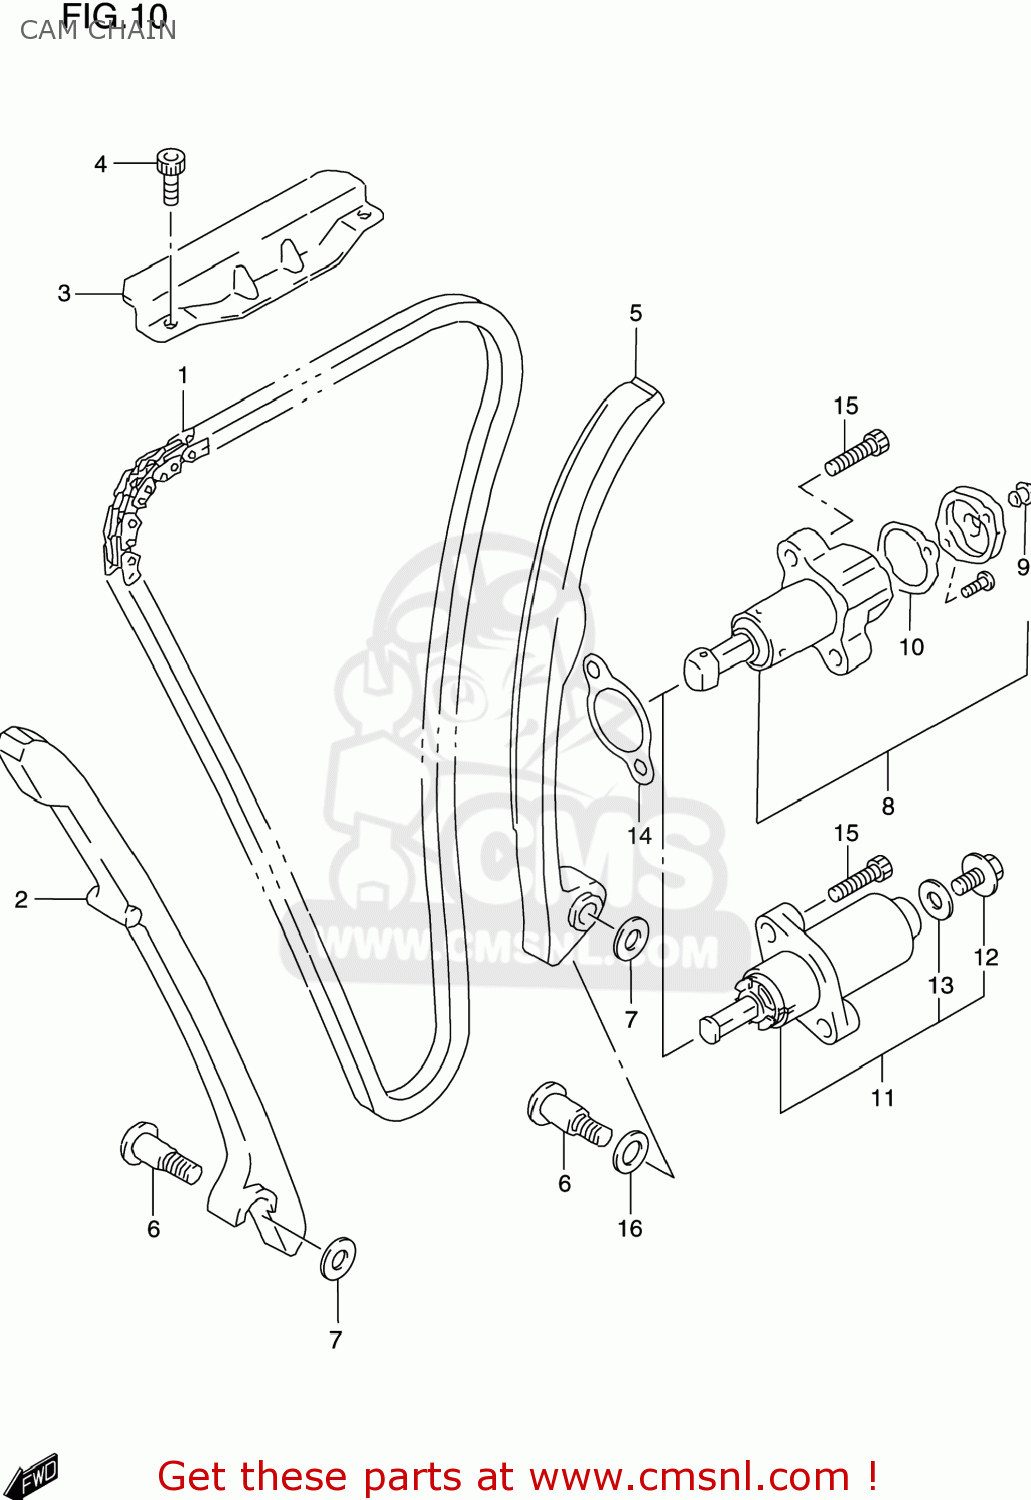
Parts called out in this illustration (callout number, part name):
1	CHAIN,CAMSHAFT DRIVE
2	GUIDE,CAM CHAIN NO.1
3	GUIDE,CAM CHAIN NO.2
4	BOLT,STRANGER
5	TENSIONER,CAM CHAIN
6	BOLT,CAM CHAIN TENSIONER
7	WASHER
8	ADJUSTER ASSEMBLY,TENSIONER
9	PLUG,ADJUSTER
10	GASKET,ADJUSTER CAP (NAS)
11	ADJUSTER ASSY,TENSIONER
12	PLUG,TENSIONER ADJUSTER
13	GASKET,TENSIONER ADJUSTER
14	GASKET,TENSIONER ADJUSTER (NAS)
15	BOLT
16	WASHER
